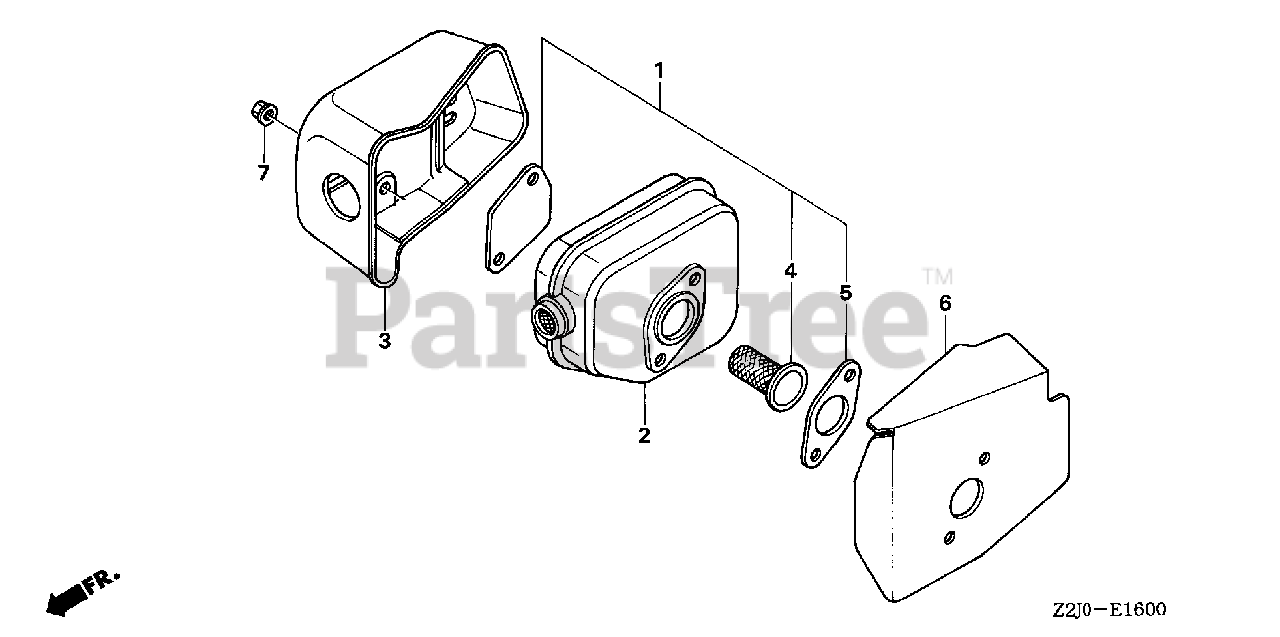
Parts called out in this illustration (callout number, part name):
1	ARRESTER KIT, SPARK
2	MUFFLER
3	PROTECTOR, MUFFLER
4	ARRESTER KIT, SPARK
5	GASKET, MUFFLER
6	GASKET, MUFFLER
7	NUT, SELF-LOCK (6MM)
